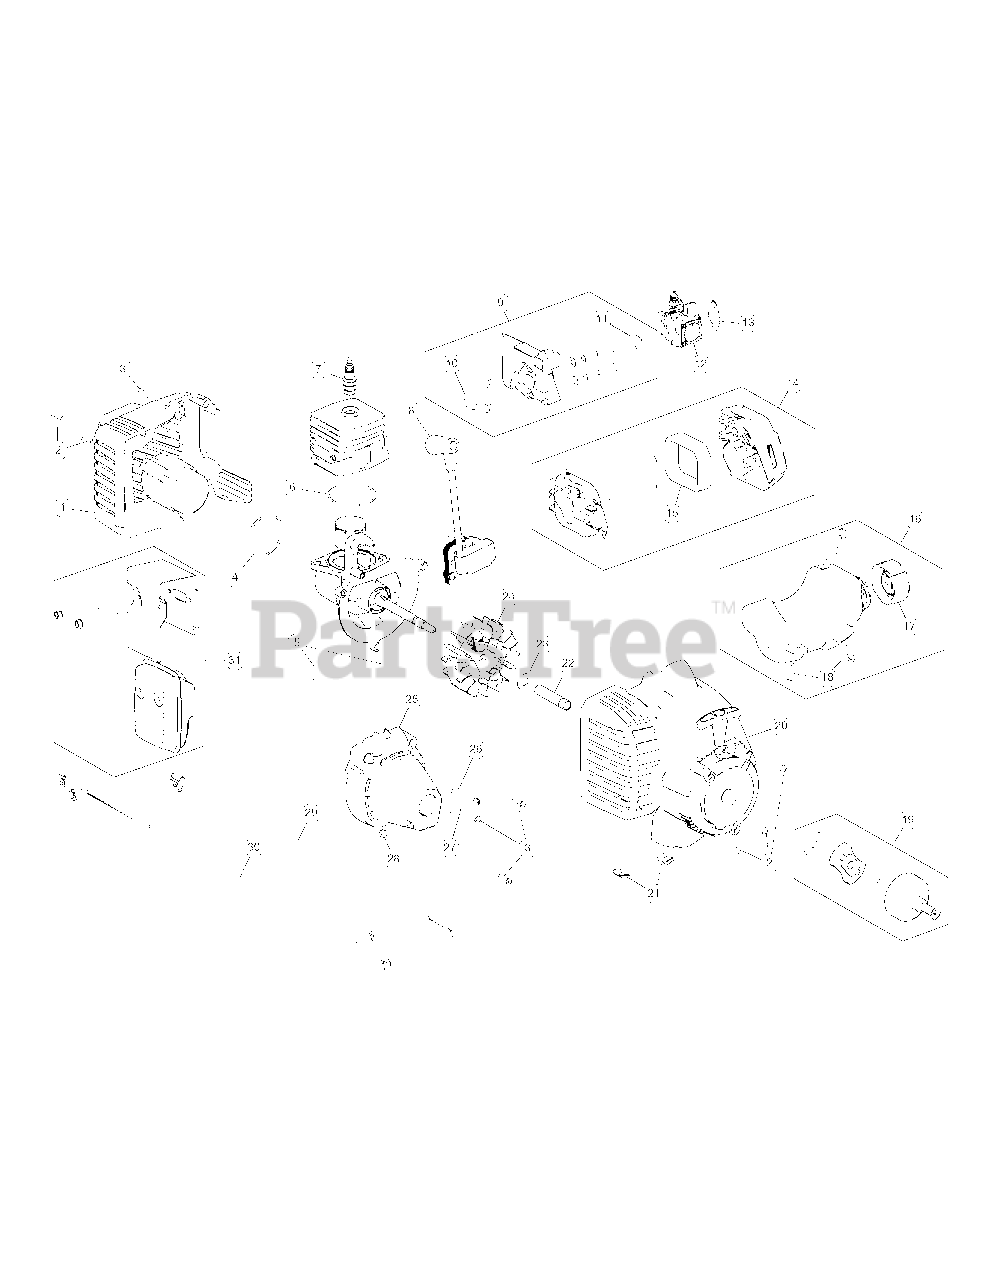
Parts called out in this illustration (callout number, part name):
1	Rear Cover Assembly (Incl. 2 & 3)
2	Housing Screw
3	Cover Screw
4	O-Ring
5	Crankcase Bolt
6	Crankcase O-Ring
7	Spark Plug
8	Module Assembly
9	Insulator Assembly (Incl. 10 & 11)
10	Insulator O-Ring
11	Carburetor O-Ring
12	Carburetor
13	Air Cleaner Gasket
14	Aircleaner Cover Assembly (Incl. 15)
15	Aircleaner Filter
16	Fuel Tank Assembly (Incl. 17 & 18)
17	Fuel Tank Cap
18	Fuel Tank Screw
19	Clutch Assembly
20	Starter Housing (Incl. 2 & 21)
21	U-shaped Nut
22	Spacer
23	Washer
24	Flywheel Assembly
25	Clutch Cover (Incl. 3)
26	Anti-rotation Screw
27	Clamp Screw
28	Clamp Nut
29	Throttle Cable
30	Lead Wires
31	Muffler Assembly
